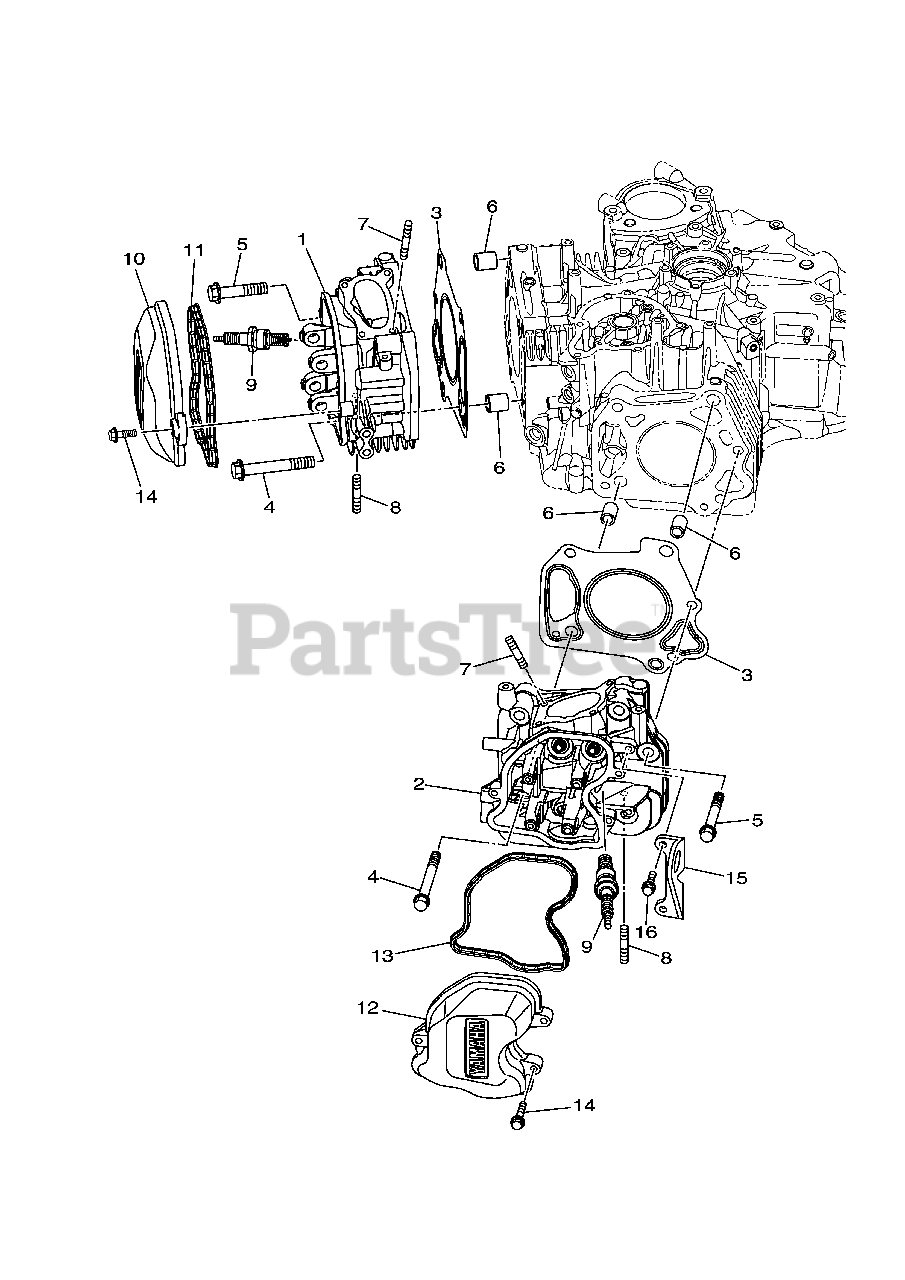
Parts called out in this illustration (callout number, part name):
1	HEAD, CYLINDER 1
2	HEAD, CYLINDER 2
3	GASKET, CYLINDER HEAD 1
4	BOLT, FLANGE
5	BOLT, FLANGE
6	PIN, DOWEL
7	BOLT, STUD
8	BOLT, STUD
9	PLUG, SPARK
10	COVER, CYLINDER HEAD 1
11	SEAL, CYLINDER 1
12	COVER, CYLINDER HEAD 2
13	SEAL, CYLINDER 2
14	BOLT, FLANGE
15	HANGER, ENGINE
16	BOLT, FLANGE
